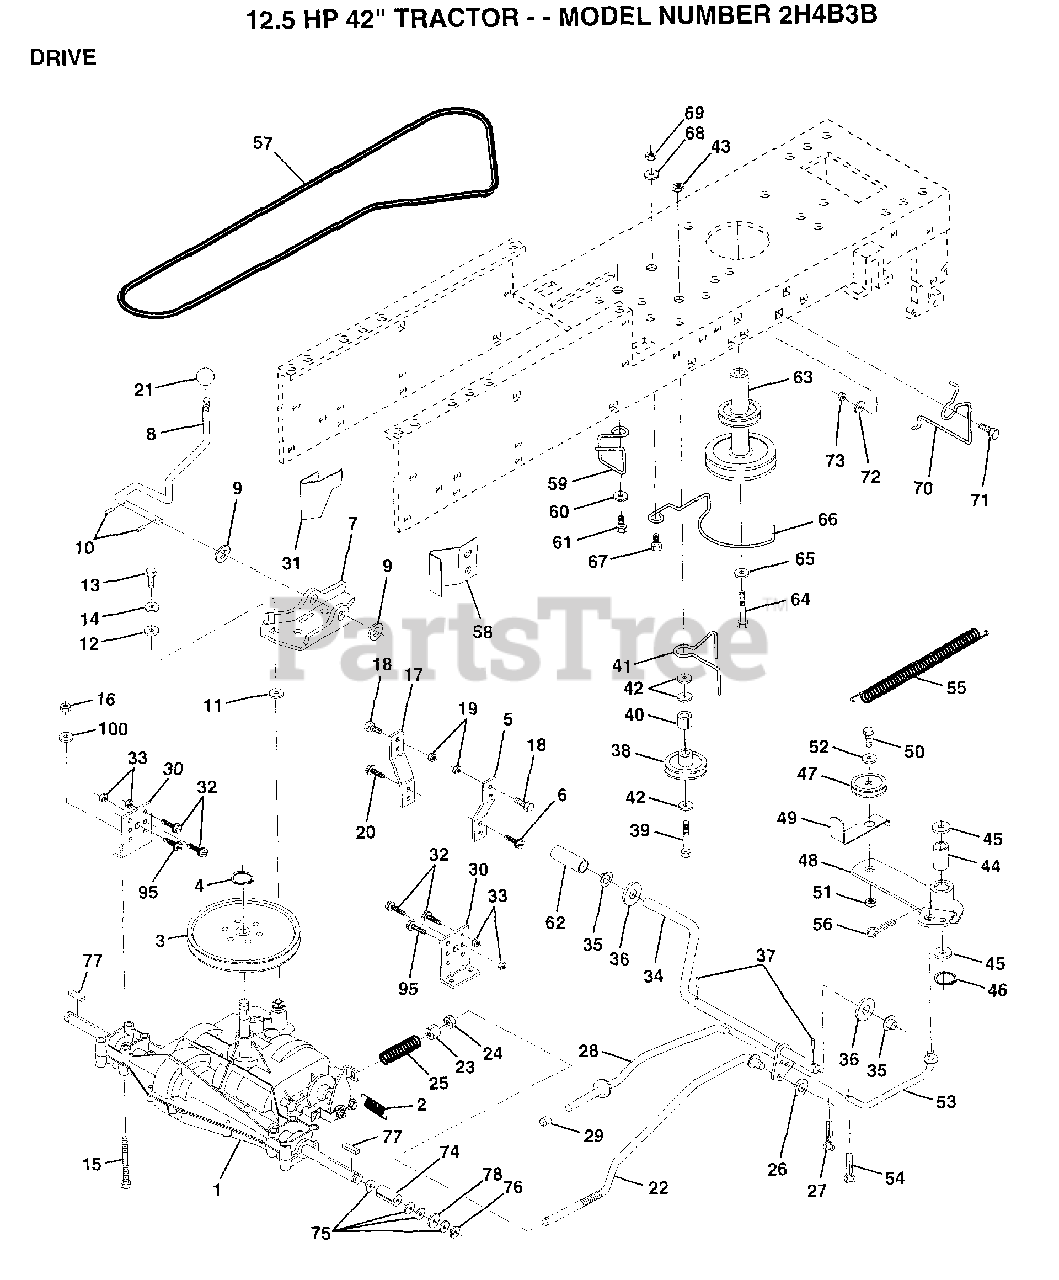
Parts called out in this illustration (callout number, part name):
3	PULLEY TRANS
5	STRAP TORQUE
6	SCREW
9	WASHER
10	PIN COTTER 1/8
11	WASH-SHFT PLT LT
12	WASHER
14	LOCKWASHER
15	BOLT HEX
17	STRAP TORQUE
18	BOLT
19	NUT
20	SCREW
21	KNOB T (1/2-HOLE)
22	BRAKE ROD
23	NUT
24	NUT
25	SPRING ROD LT
26	WASHER
27	COTTER PIN
28	ROD PARK BRAKE
29	PLUNGER CAP T
30	TRANSAXLE MTG BKT
31	"KEEPER,BELT LH T"
32	BOLT
33	NUT
35	NYLON BEARING
36	WASHER LT
38	PULLEY.IDLER.FLAT
39	BOLT
40	SPACER T
41	BELT KEEPER LT
42	WASHER
43	NUT
44	"LY, BEARING"
45	WASHER LT
46	KLIP RING
48	ARM IDLER
49	RETAIN BELT
52	WASHER
53	"LINK, CLUTCH T"
54	COTTER PIN
55	"SPRING, RETURN LT"
56	COTTER PIN
58	"KEEPER,BELT RH T"
59	KEEPER BELT CNTSP
60	WASHER
61	SCREW
62	PEDAL COVER T
63	PULLEY.ENGINE
64	BOLT
65	LOCKWASHER
66	KEEPER.BELT.ENG.L
67	BOLT
68	WASHER
70	KEEPER BELT ENG
71	BOLT
72	WASHER
74	SPACER LT
75	WASHER
76	E-RING LT
77	SQUARE KEY
78	WASHER
95	SCREW
100	WASHER M
